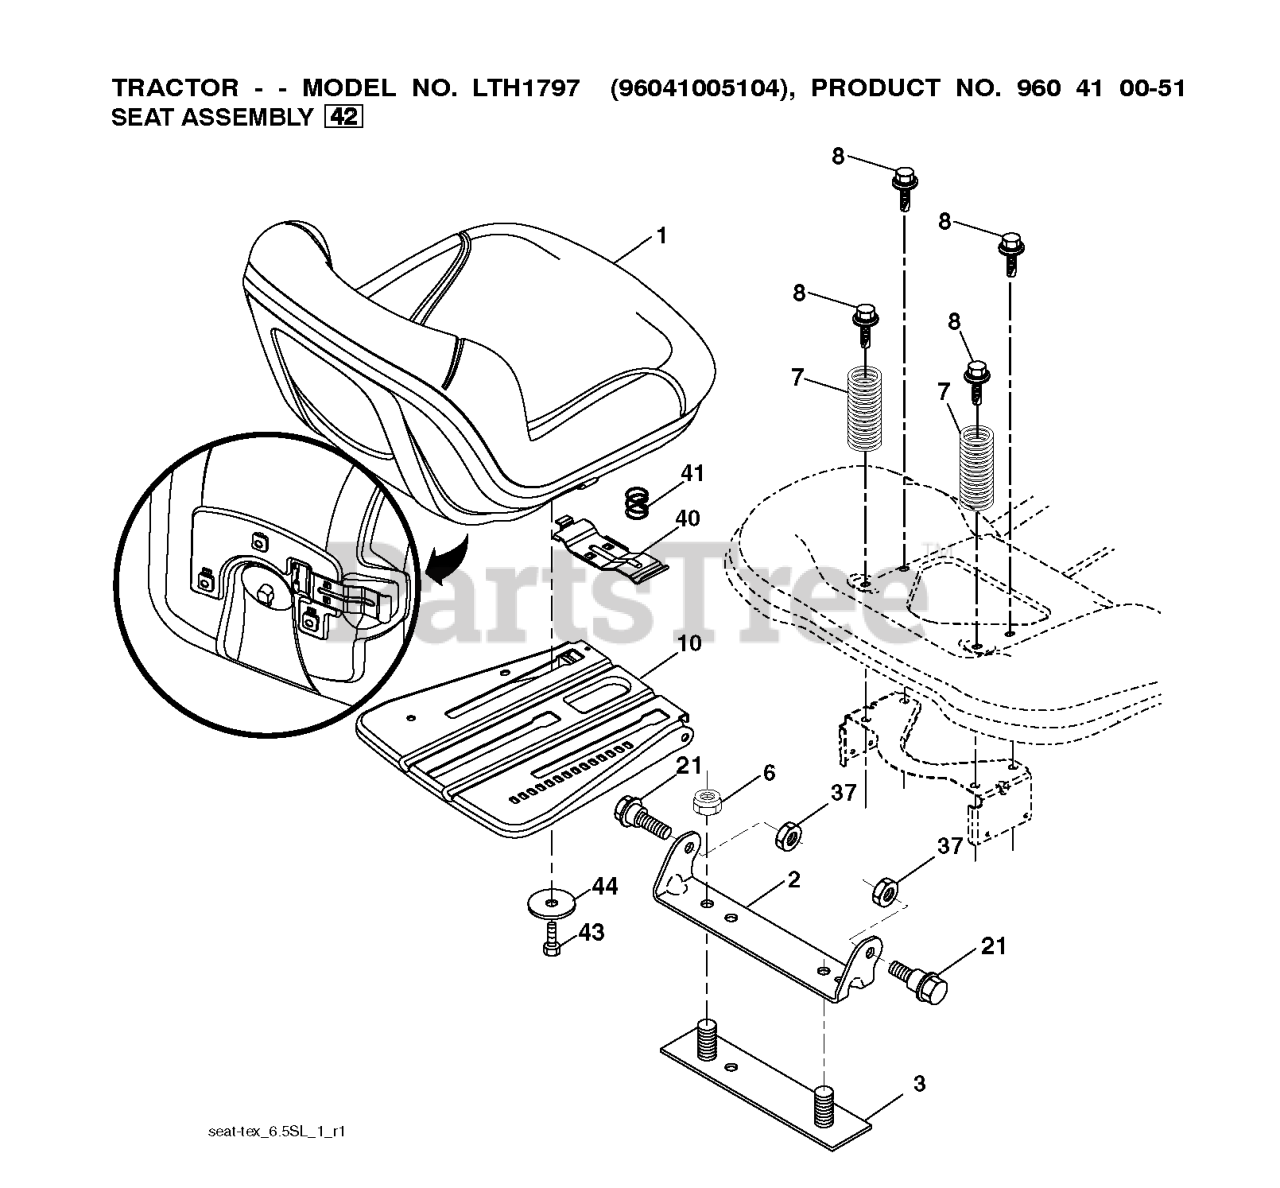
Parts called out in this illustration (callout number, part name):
1	RP SEAT.TH130.GRY.MILSCO.
2	BRKT.PIVOT.FENDER
3	STRAP
6	NUT
7	SPRING COMPRESSION
8	BOLT.5/16-18UNCX3/4 W/SEMS.BLK
10	PAN.ASM.SEAT.3PT
21	BOLT.SHOULDER.5/16-18
37	NUT.71038.31-18.HEX.NYLOCK
40	HANDLE.SLIDE.SEAT.TEX.BLACK
41	SPRING.LATCH.SEAT.TEX
44	WASHER 13/32 X 2-3/8 X 12GA
